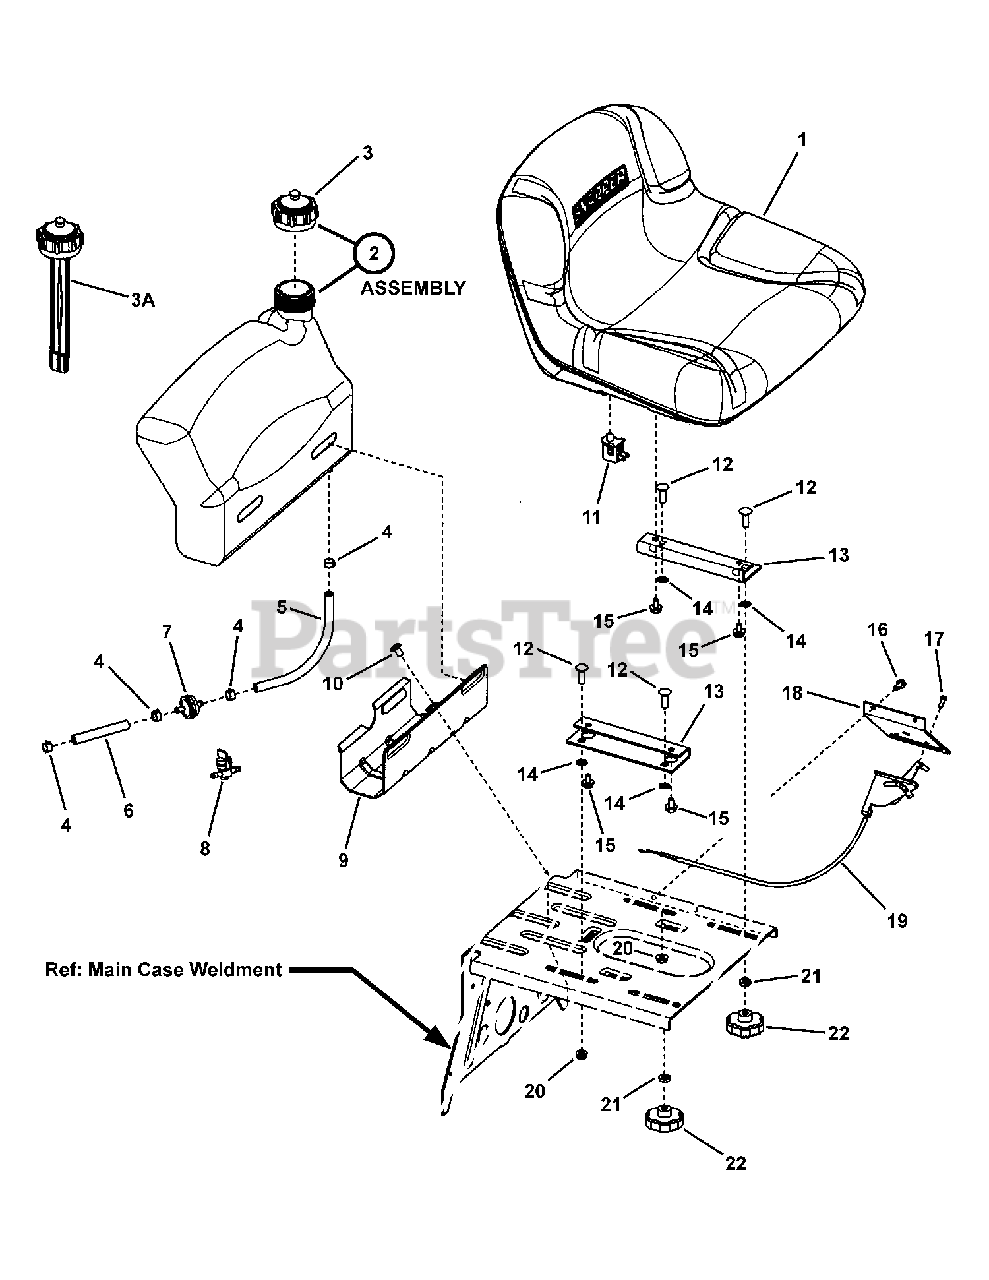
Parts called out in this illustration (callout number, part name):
1	SEAT, Operator (11.58" tall) (shown) (Michigan V-2400 Series)
1	SEAT, Operator (9.30" tall) (Michigan V-2300 Series)
2	ASSEMBLY, Fuel Tank (Includes item 3)
2	ASSEMBLY, Fuel Tank with Gauge (Includes item 3A)
3	CAP, Fuel Tank
3A	CAP, Fuel Tank w/Gauge
4	CLAMP, Fuel Line
5	HOSE, Fuel, Low Perm (1/4" I.D. x 8-1/2" long)
6	HOSE, Fuel (1/4" I.D. x 3-1/2" long)
7	FILTER, Fuel (In-Line)
8	VALVE, Fuel Shut-Off (Accessory)
9	BRACKET, Fuel Tank (Rear)
10	SCREW, 5/16-18 x 1/2" Pan Head Self-Tap (Torx #T-40)
11	SWITCH, Seat (NC)
12	BOLT, 5/16-18 x 1" Square Neck Carriage, GR 5 YZ
13	BRACKET, Seat
14	RETAINER, 5/16" Bolt
15	BOLT, 5/16-18 x 1/2" Hex Flange Nyloc
16	SCREW, 1/4-20 x 1/2" Hex Washer Self-Tap
17	SCREW, #10-24 x 1/2" Hex Washer Self-Tap (Torx)
18	PLATE, Throttle Control
19	CONTROL, Throttle (23.6" long)
20	NUT, 5/16-18 Hex Flange Top Lock
21	SPACER, .33 x .63 x .156
22	KNOB, Fluted, 5/16-18 internal thread (2.15 O.D.)
